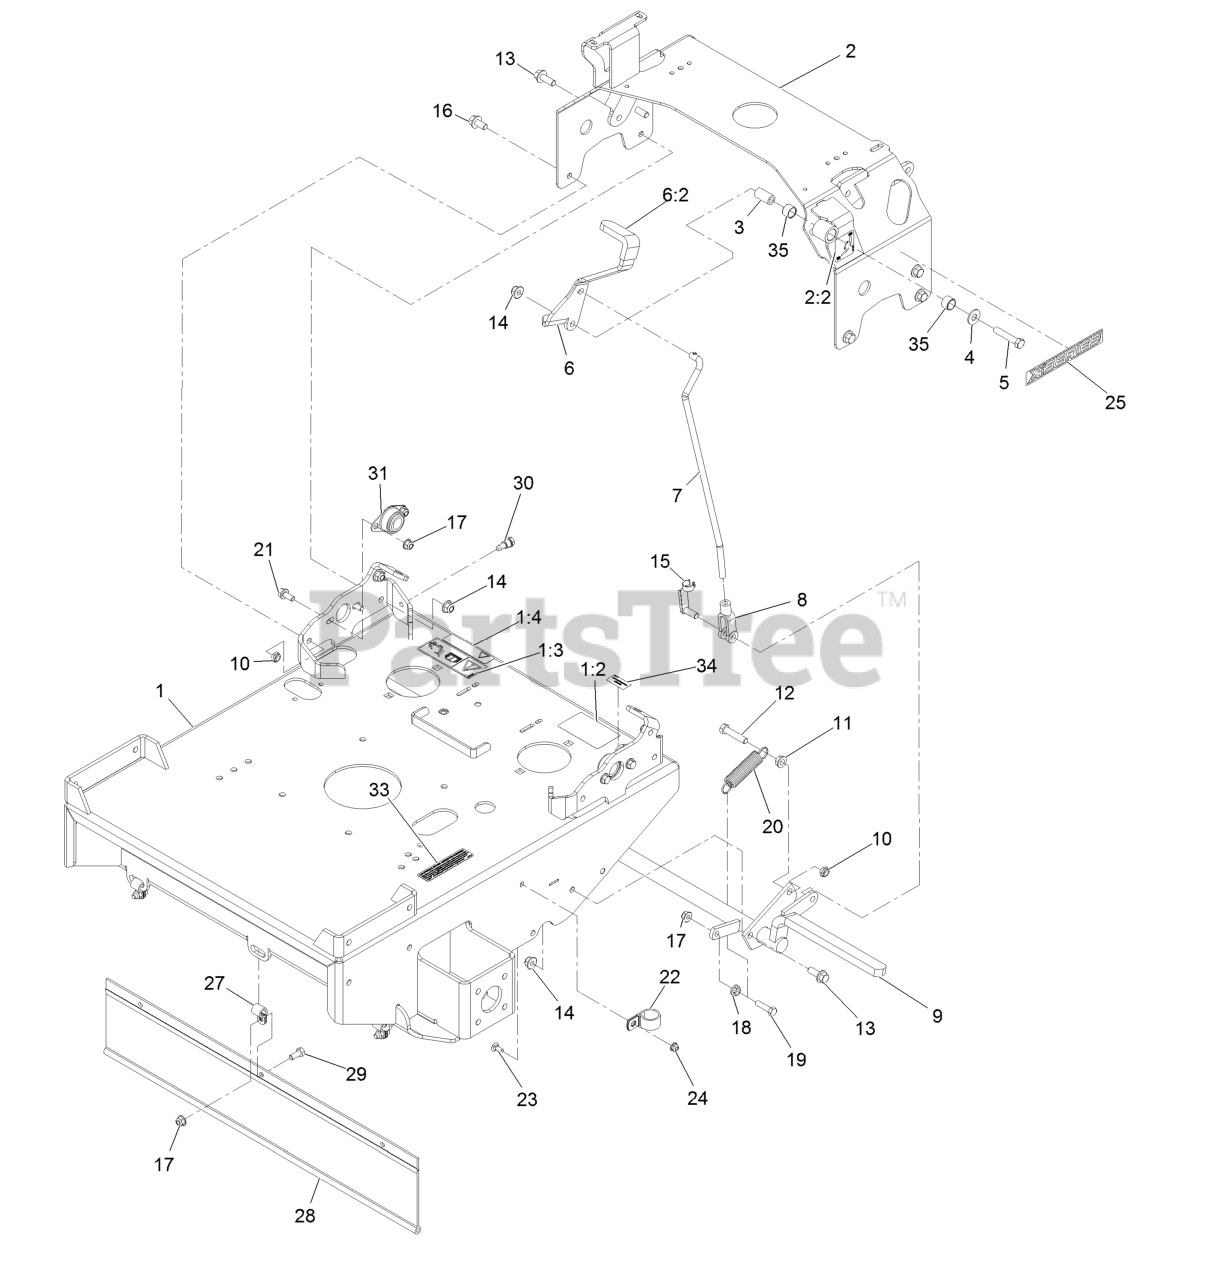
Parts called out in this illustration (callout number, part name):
1	ASM, Engine Deck W/Decals
1:2	Decal-Warning
1:3	Decal-Warning, Sulky
1:4	Decal-Drive Release
2	ASM, Tank Support W/Decal
2:2	Decal-Park Brake, CE
3	Bushing-Pivot
4	Washer-3/8 Std
5	Screw-HH 3/8-16 X 2
6	ASM, Brake Lever W/ Grip
6:2	Grip-Lever
7	Linkage-Brake
8	Yoke-Linkage, Brake
9	Wld,Brake Ttx
10	Nut-Nyloc 3/8-16 Thin
11	Nut-Whizlock 3/8-16
12	Screw-HH 3/8-16 X 1 3/4
13	Screw HHF 3/8-16 X 1
14	Nut-Nyloc 3/8-16 Flg
15	Pin-Clevis Spring 3/8
16	Screw-HH Flg 3/8-16 X 3/4
17	Nut-Nyloc 5/16-18 Flg
18	Nut-Whizlock 5/16-18
19	Screw-HH 5/16-18 X 1 1/4
21	Screw-HH Flg 5/16-18 X 3/4
22	Clip-Loom
23	Bolt-Carriage 1/4-20 X 5/8
24	Nut-Nyloc 1/4-20 Flg
25	Decal-X-Series
27	Clip-Loom
28	Shield, Drag
29	Screw-HH 5/16-18 X 3/4
30	Bolt-Shoulder
31	Bearing-Flanged
33	Decal-Arrester, Spark
34	Decal-Patent
35	Sleeve-Bushing
